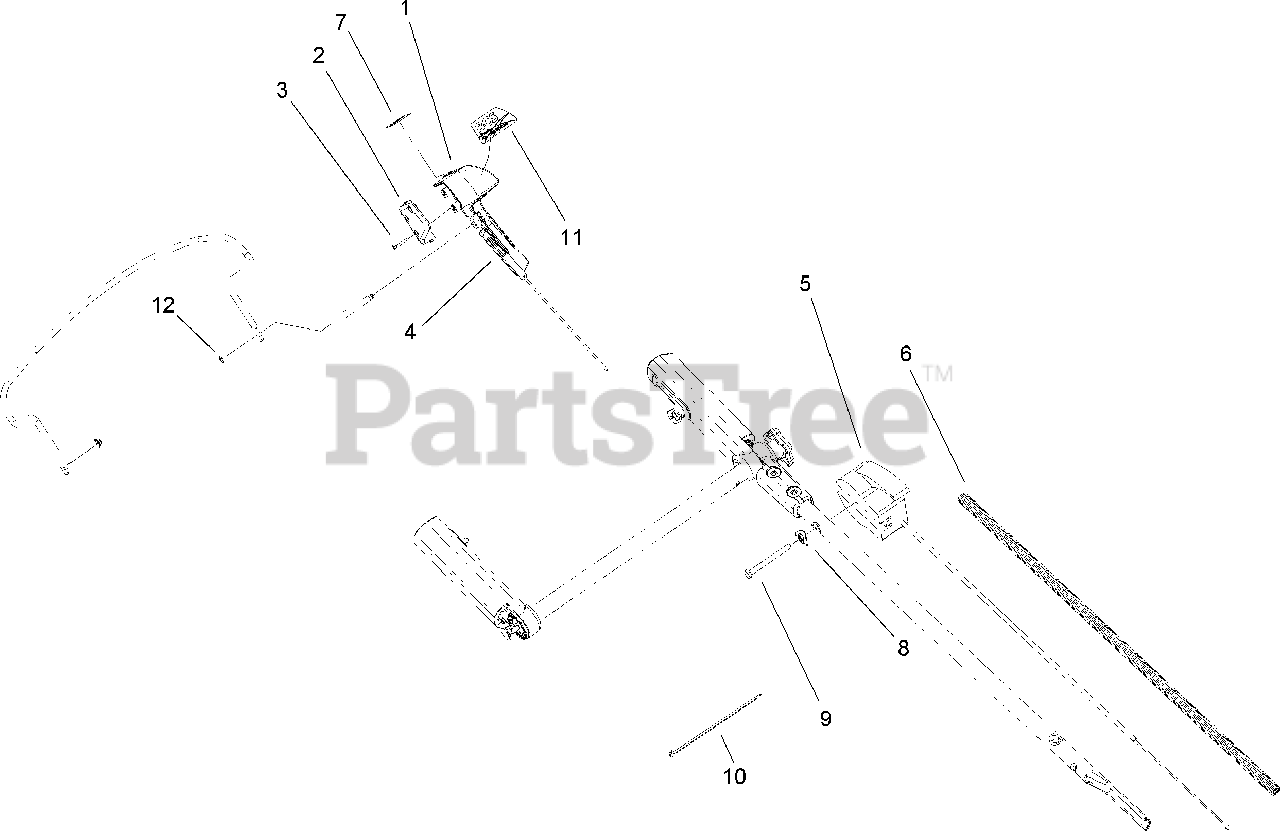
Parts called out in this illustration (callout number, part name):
1	PIVOT ASM
2	COVER-SWITCH
3	SCREW-PPH
4	CABLE-BRAKE
5	CABLE-THROTTLE
7	DECAL-BLADE, BBC
9	SCREW-HH
10	STRAP-TIE
11	DECAL-CONTROL, BLADE
12	RING-RETAINING
